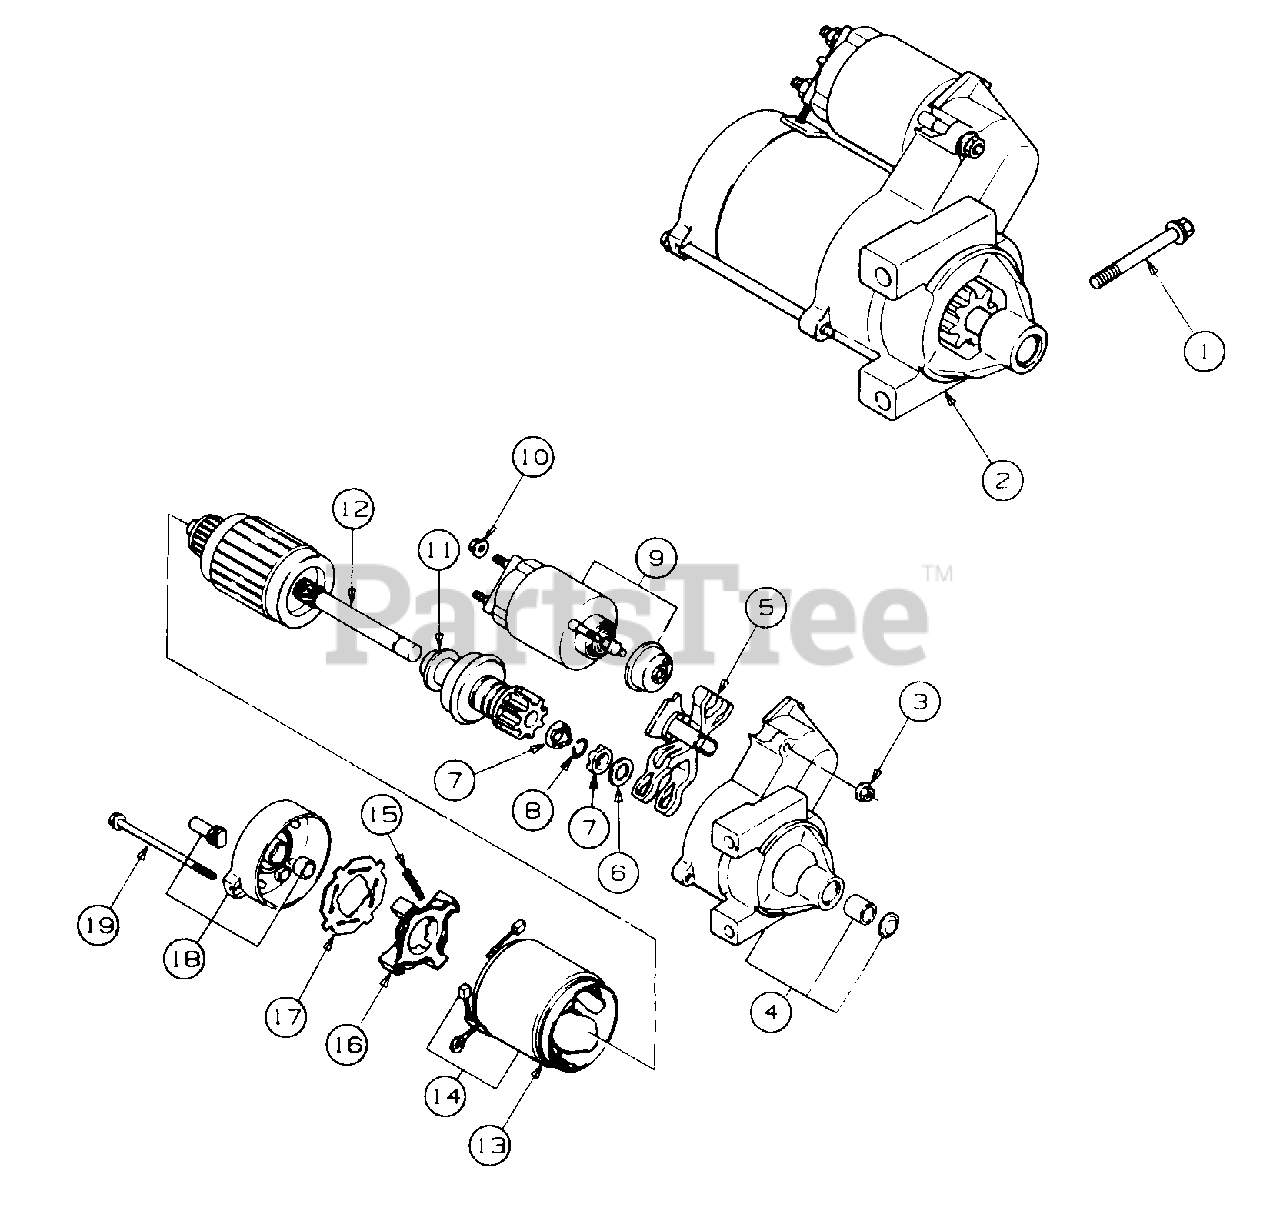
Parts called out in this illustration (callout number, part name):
1	Screw, Bendix Starter M8 x 1.25 x 80.6
2	Starter, Solenoid Shift Assy
3	Nut, Starter
4	Cap, Drive End
5	Lever, Starter Drive
6	Washer, Thrust
7	Nut, Stop Collar
8	Ring, Retainer
10	Nut, Starter
11	Drive, Pinion
12	Armature, Starter
14	Kit, Brush
15	Spring, Brush
16	Holder, Brush
18	Cap, Commutator End
